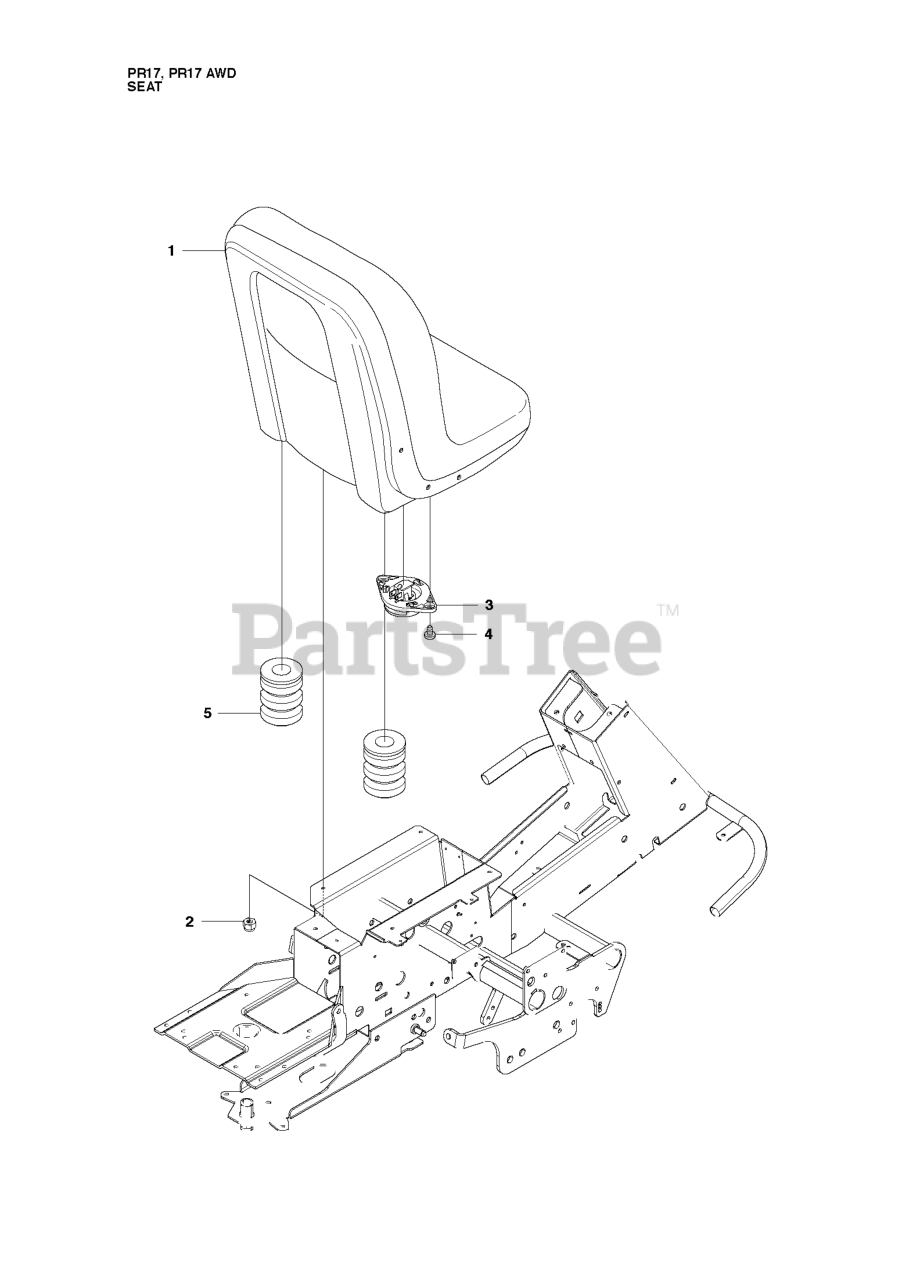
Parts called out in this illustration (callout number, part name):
2	LOCKNUT M8
3	ANTI-START SWITCH CPL
4	SCREW
